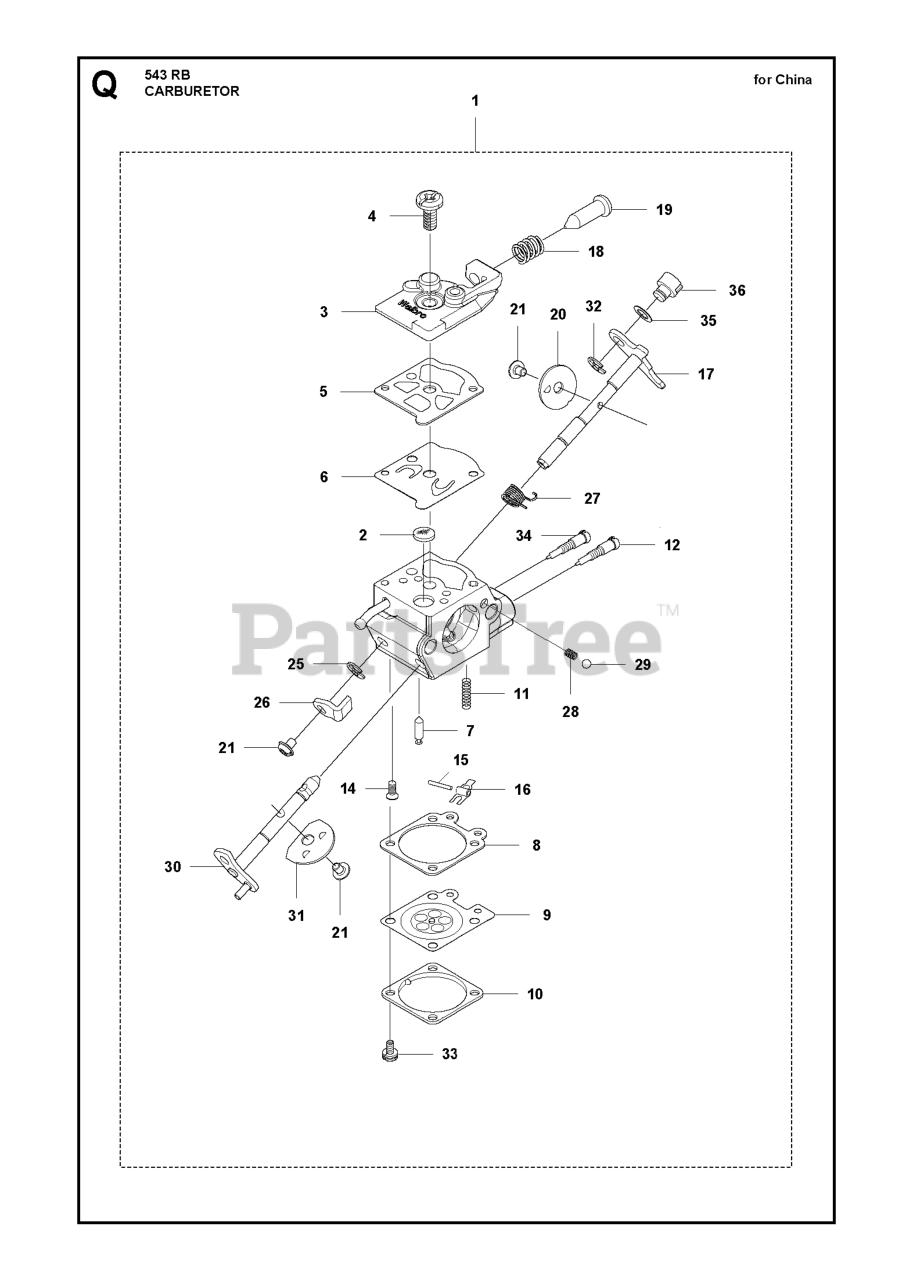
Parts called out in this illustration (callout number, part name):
2	SCREEN
3	COVER
4	SCREW
5	GASKET
6	DIAPHRAGM, FUEL PUMP
7	VALVE INLET
8	GASKET
9	DIAPHRAGM
10	COVER
11	SPRING
14	SCREW
15	PIN
16	LEVER
17	SHAFT ASSY THROTTLE
18	SPRING
19	SCREW, IDLE
21	SCREW
25	E-RING
26	LEVER THROTTLE
27	SPRING
28	CHOKE SPRING
29	BALL
30	SHAFT ASSY CHOKE
32	RING
33	SCREW ASSY
35	WASHER
36	SWIVEL
